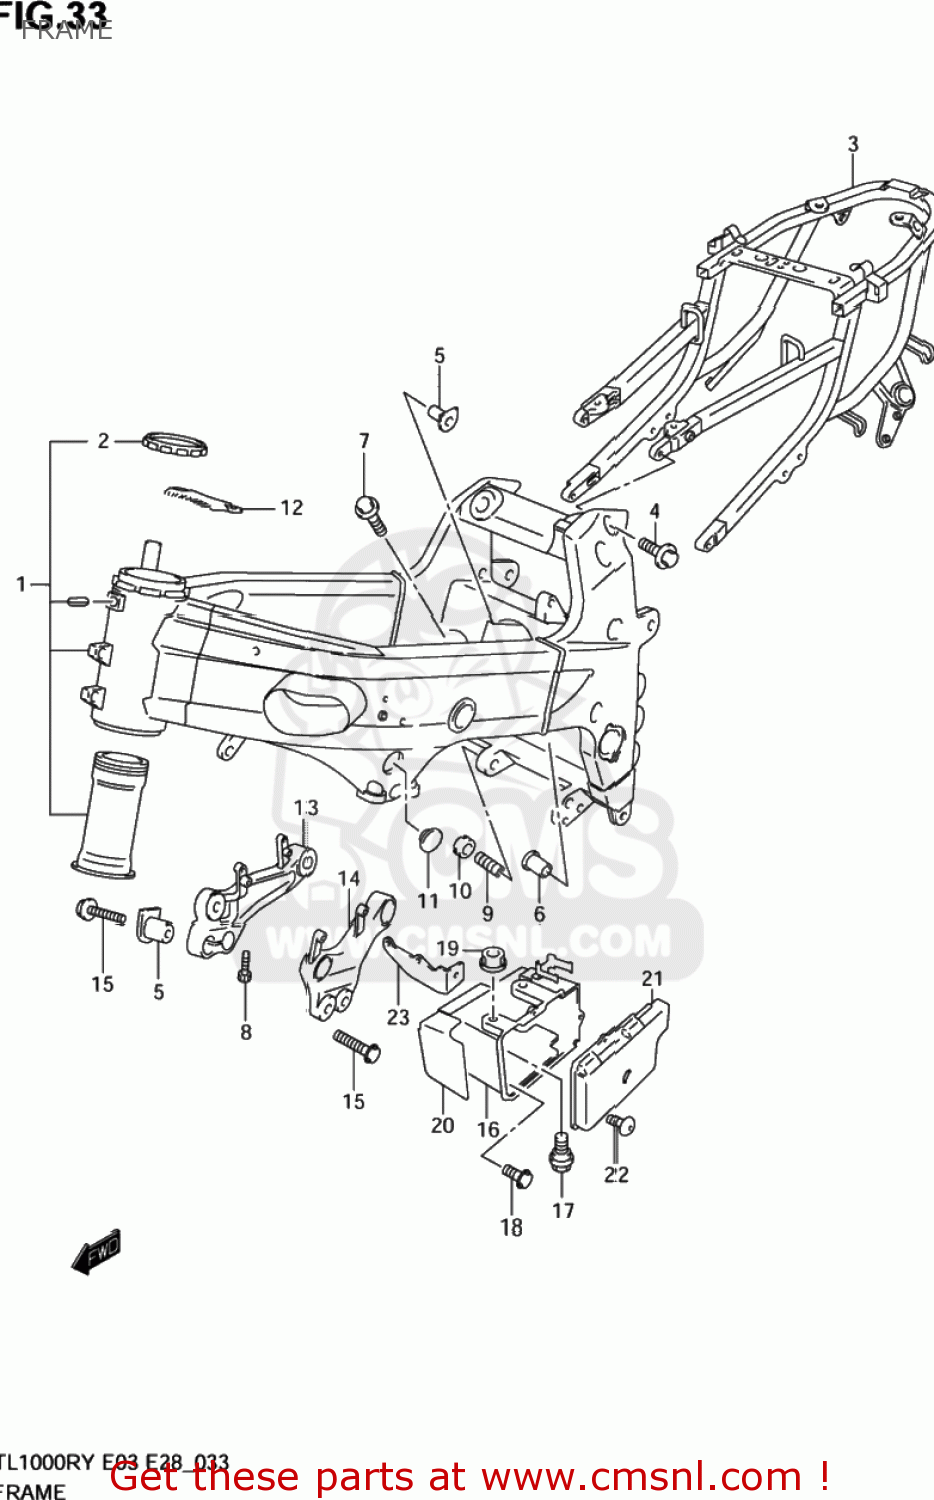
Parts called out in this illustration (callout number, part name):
1	FRAME SET
2	NUT,STEERING STEM PIPE
3	RAIL,SEAT
4	BOLT(10X30)
5	SPACER,ENG MTG FR,R
6	SPACER,ENG MTG RR UP,R
7	BOLT
8	BOLT
9	BOLT,CRANKCASE ADJUST
10	NUT,CRANKCASE ADJUST
11	CAP
12	PLATE,STEERING STEM NUT LOCK
13	BRACKET,ENGINE MOUNTING FR,R
14	BRACKET,ENGINE MOUNTING FR,L
15	BOLT
16	HOLDER,BATTERY
17	BOLT
18	BOLT(6X16)
19	NUT
20	SHIELD,BATTERY HOLDER HEAT
21	CAP,BATTERY HOLDER
22	SCREW 5X12
23	PLATE,BATTERY HOLDER LWR
